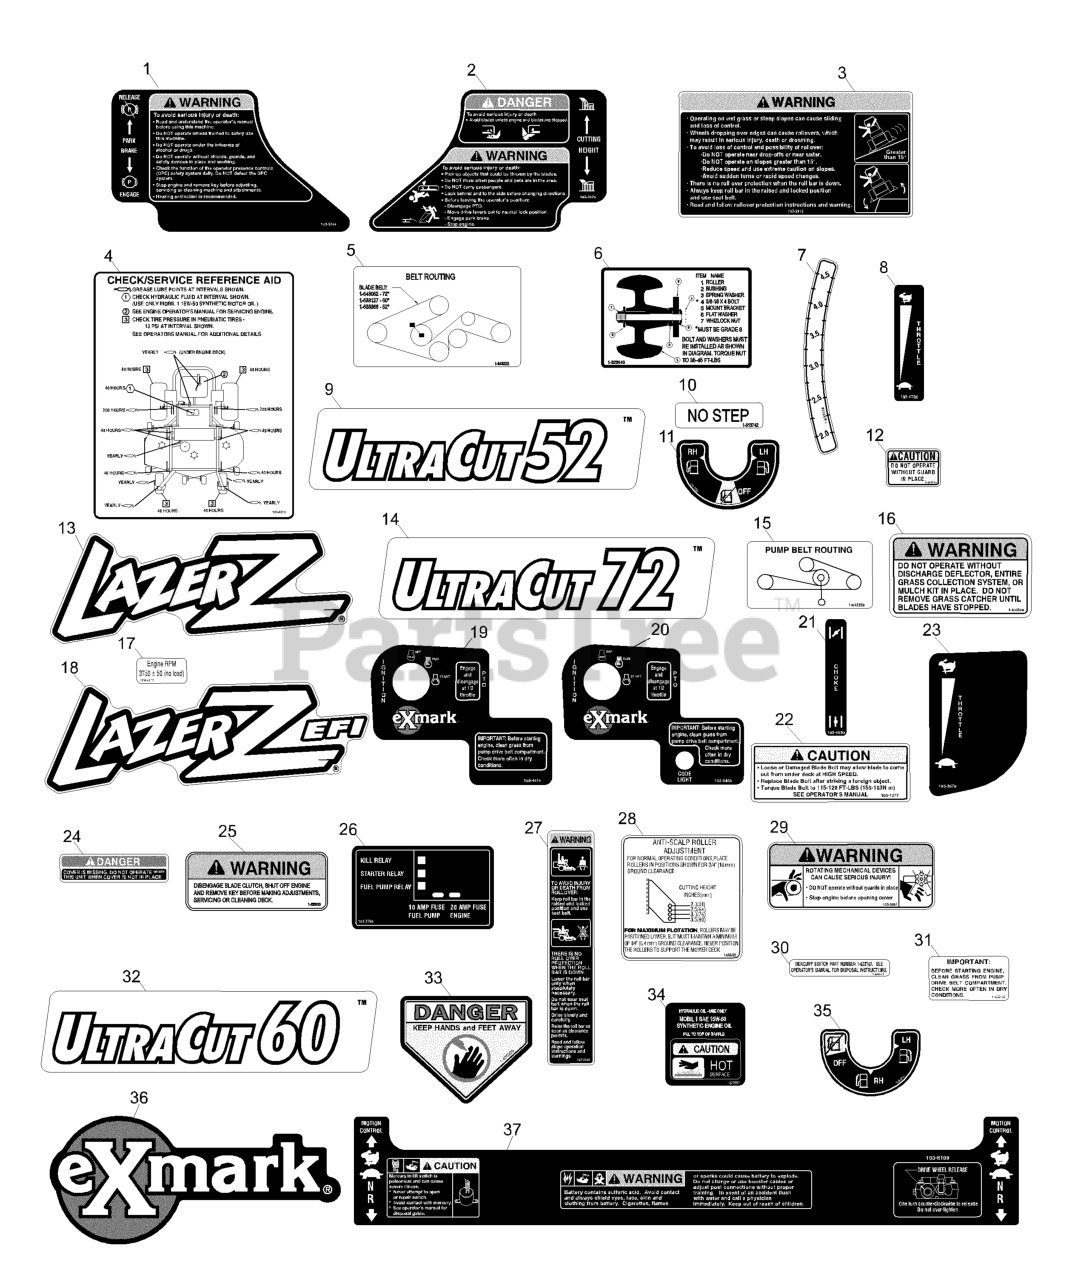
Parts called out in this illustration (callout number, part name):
1	DECAL,PARK BRAKE
2	DECAL,CUTTING HEIGHT
3	DECAL-WARNING
4	DECAL,CHECK SERVICE LZ
5	DECAL,BELT ROUTING
6	DECAL,ROLLER MOUNTING
7	DECAL-HEIGHT, DECK
8	DECAL,THROTTLE ONLY
9	DECAL,ULTRACUT 52
10	DECAL,NO STEP
11	DECAL-VALVE, FUEL
12	DECAL-GUARD
13	DECAL,LAZER MODEL
14	DECAL,ULTRACUT 72
15	DECAL-ROUTING, BELT
16	DECAL-WARNING, DISCHARGE
18	DECAL,EFI
19	DECAL,IGNITION/PTO
20	DECAL,IGNITION/PTO EFI
21	DECAL,CHOKE
22	DECAL,BOLT TORQUE
24	DECAL-COVER, MISSING
25	DECAL,WARNING
27	DECAL-WARNING, FOLDING RO
28	DECAL,ANTISCALP
29	DECAL-DEVICES, ROTATING
30	DECAL-SWITCH, MERCURY
31	DECAL-IMPORTANT
32	DECAL,ULTRACUT 60
33	DECAL-DANGER
35	DECAL-VALVE, FUEL
36	DECAL,EXMARK LOGO
